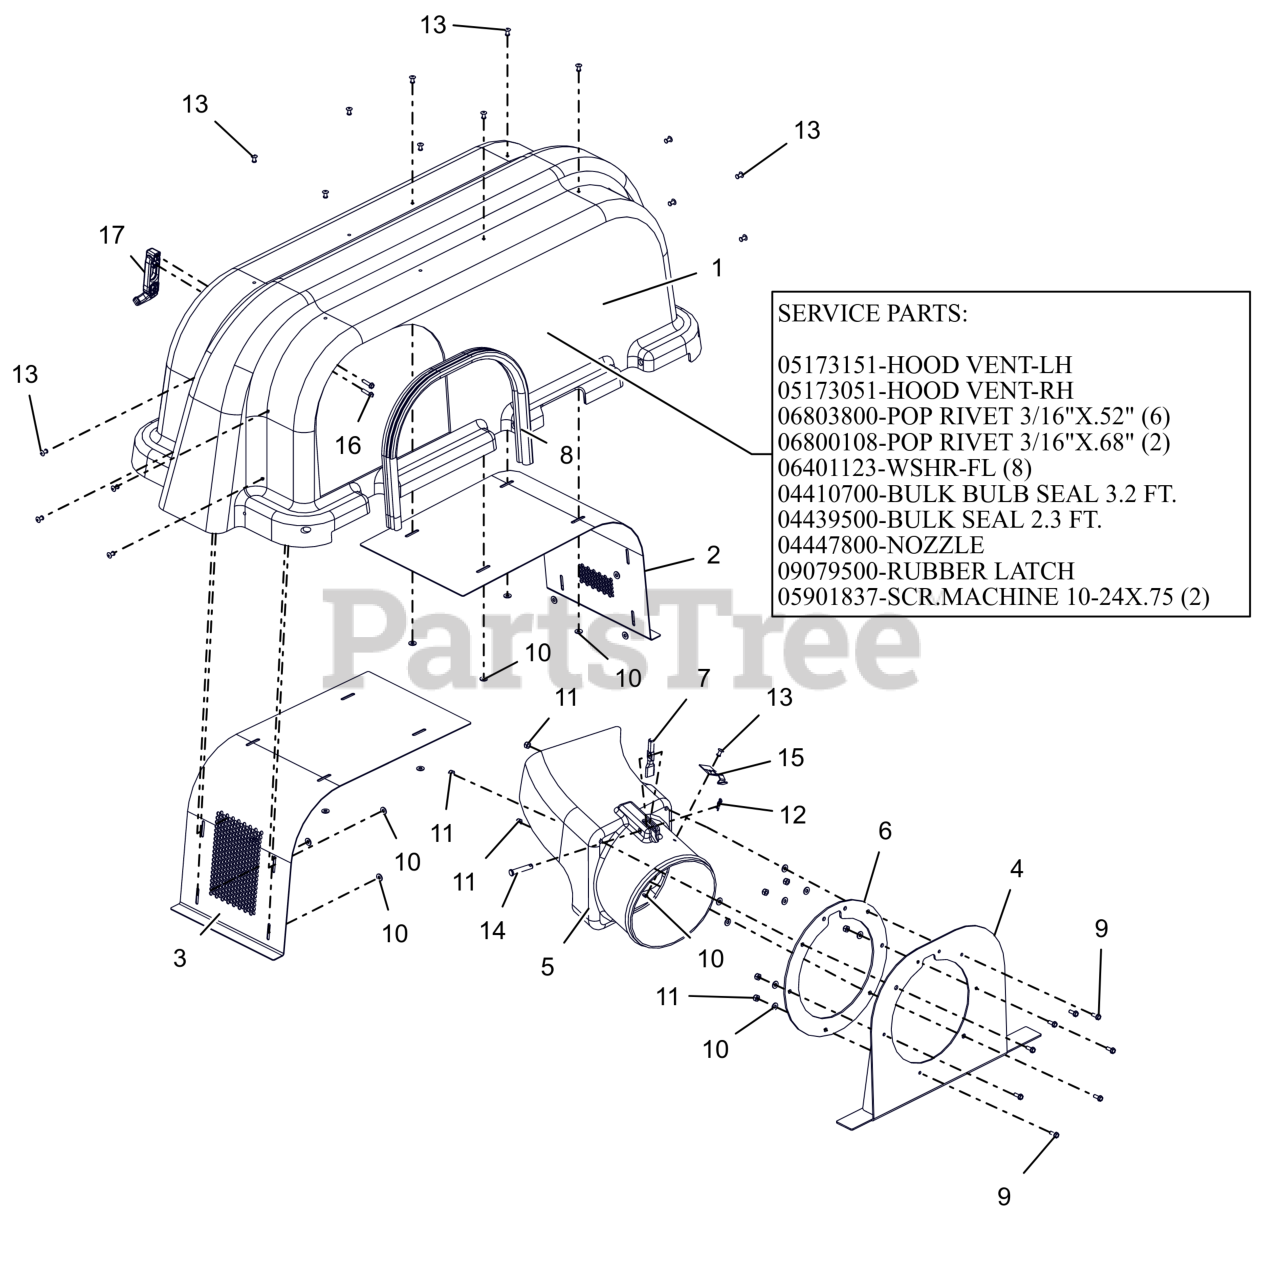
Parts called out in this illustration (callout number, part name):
1	KIT, HOOD ASSEMBLY
2	VENT, BAGGER LH HOOD
3	VENT, BAGGER RH HOOD
4	WLDMT, TUBE SUPPORT
5	BOOT, UPPER
6	SEAL, UPPER BOOT
7	INDICATOR, FLOW
8	SEAL, BULK
8	SEAL, BULB - BAGGER HOOD
9	BLT, HWH #10-24X.50 ZCC
10	WSHR, FLT .219X.500X.049 ZCC
11	NUT-LK-NYL #10-24 G2 ZCC
12	PIN, HAIR #225 .072X1.09
13	RVT-POP.187X.527 DOME ST
14	PIN-CLEV .309 X 1.625 YWZC
15	THUMB LATCH
16	BLT, HWH #10-24X.75 ZCC
17	LATCH, RUBBER
